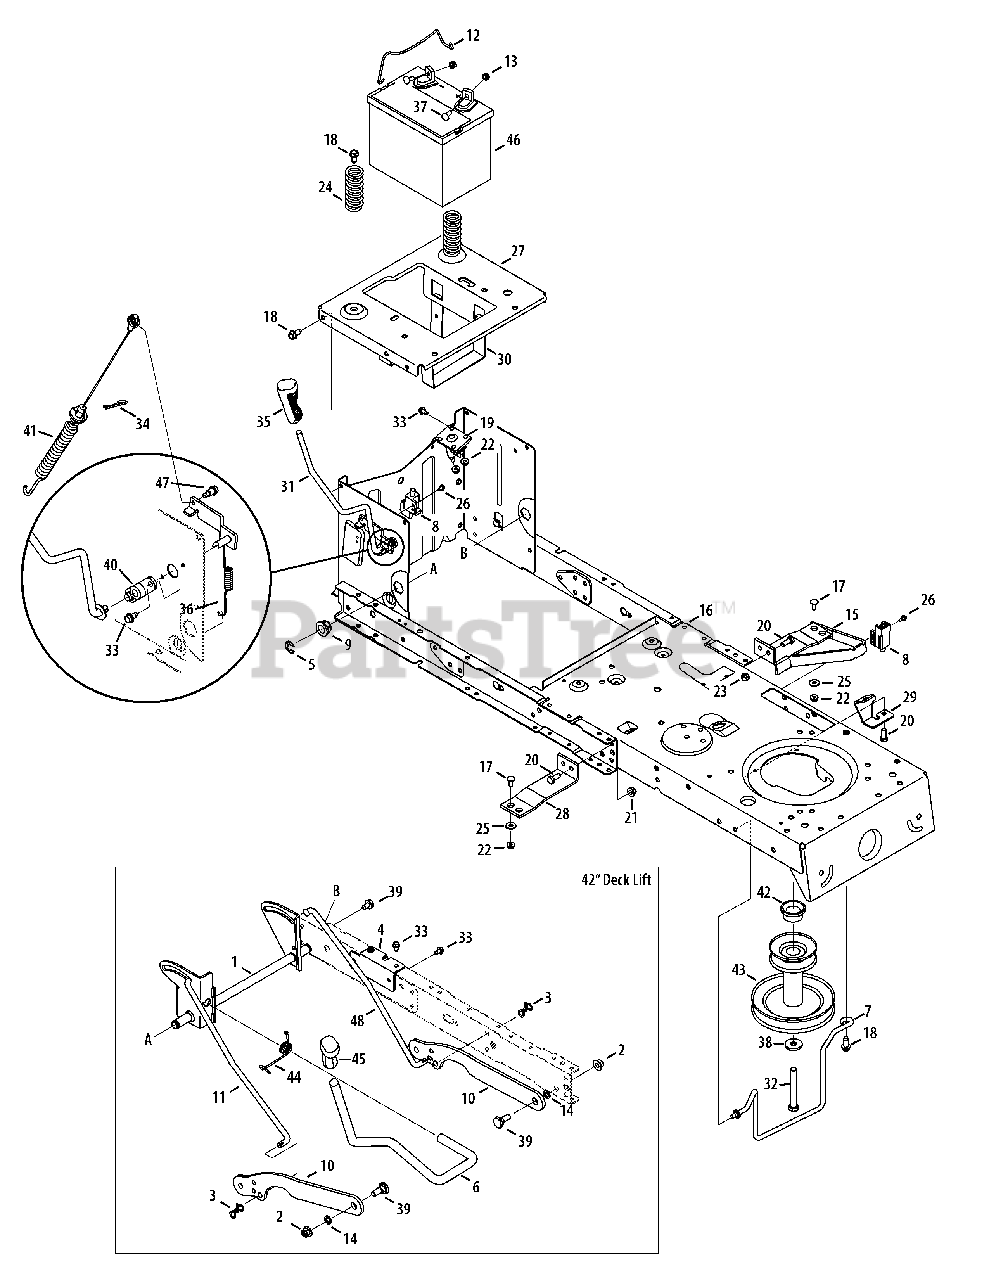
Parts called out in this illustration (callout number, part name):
1	Shaft Assembly Lift
2	Nut, Flange Lock, 3/8-16, GrF
3	Pin, Cotter, Bow Tie
4	Frame Brace Bracket
5	Ring, E-Type, .625 Dia.
6	Deck Handle, Lift, 46" Deck
7	Rod, Belt Keeper
8	Switch, Interlock
9	Bearing, Hex Flange
10	Deck Lift Link
11	Lift Rod, RH
12	Battery Hold Down Rod
13	Nut, Sems, 1/4-20
14	Washer, Flat, .385 x .62 x .063
15	Support Bracket Assembly
16	Frame Assembly
17	Screw Carriage, 1/4-20 x .75
18	Screw, 5/16-18, .750
19	12V Solenoid
20	Hex Screw, 5/16-18 x .75
21	Flange Lock Nut, 5/16-18
22	Nut, Flange Lock, 1/4-20, GrF
23	Hex Lock Nut, 5/16-18
24	Compression Spacer, 1.314 x 2.55
25	Flat Washer, .28 x .74 x .063
26	Shoulder Screw, #10-32 x .500
27	Seat Bracket, Frame
28	Bracket, Runing Board
29	Frame Support Bracket
30	Bracket, Battery
31	PTO Handle Assembly
32	Hex Screw, 7/16-20 x 3.25
33	Screw, 1/4-20, 0.500
34	Pin, Click, .092 x 1.64
35	Grip, Handle, 3/8
36	Spring, Extension
37	Screw, Carriage, 1/4-20, .75, Gr5
38	Washer, Flat, .450 x 1.250 x .164
39	Bolt, Shldr. .500 x .270 3/8-16
40	Bearing, PTO
41	Deck Engage Cable
42	Spacer, 1.010 x 1.400 x .825
43	Engine Pulley
44	Spring, Torsion 46" Deck
45	Grip, Handle, 5/8
46	Battery, 155 CCA
47	Shoulder Bolt, 1/4-28 x .342 x .335
48	Lift Rod, LH
